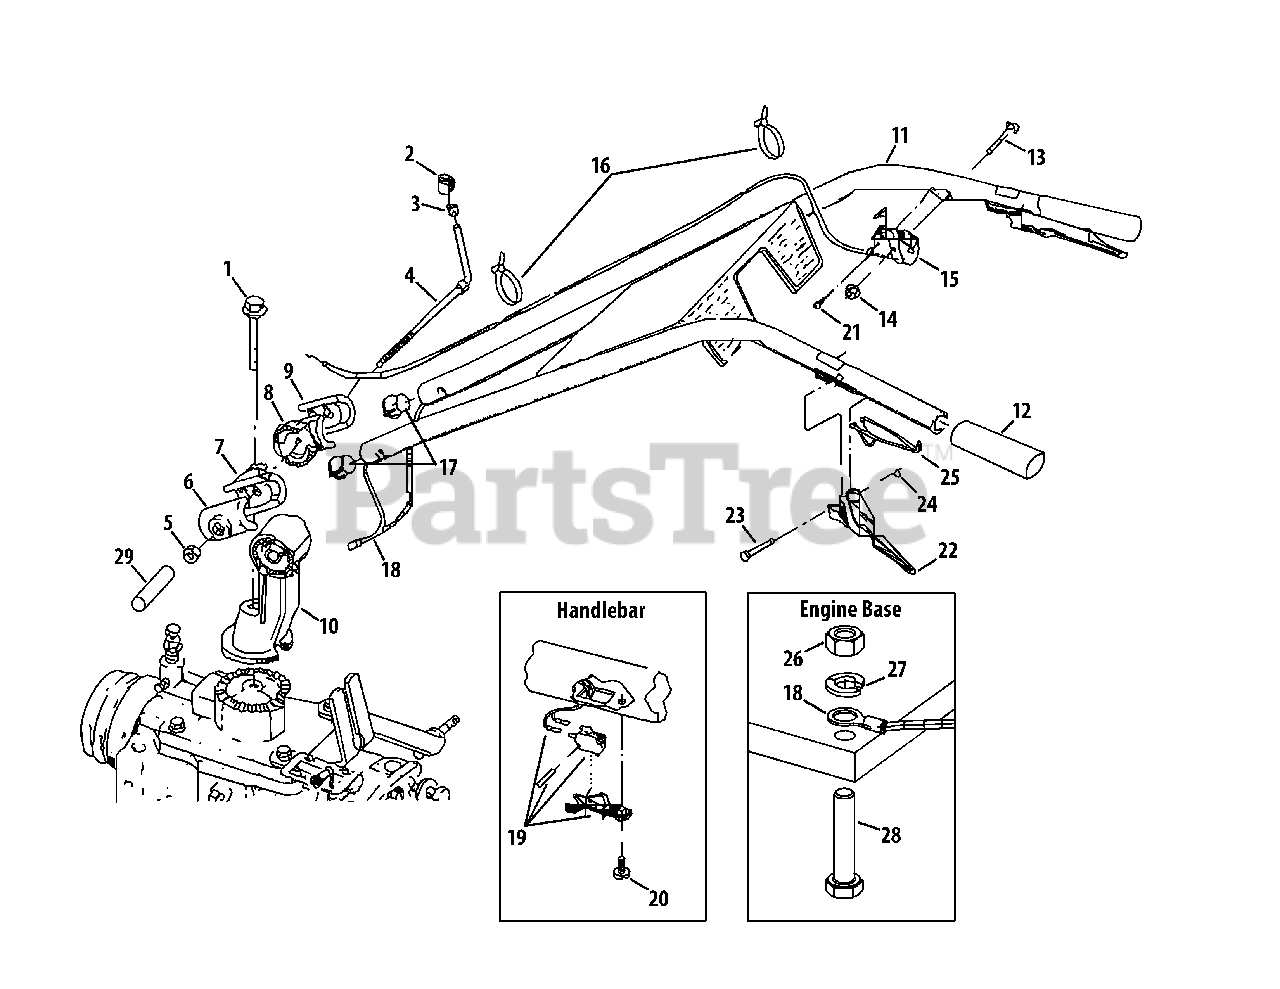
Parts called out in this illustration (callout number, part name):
1	Hex Bolt, 1/2-13 x 3-1/2
2	Handlebar Height Adjustment Knob
3	Retaining Ring
4	Handlebar Height Adjustment Stud
5	Hex Nut, 1/2-13
6	Handlebar Hgt, Adj. Clamp (LT)
7	Handlebar Hgt. Adj. Ratchet (LT)
8	Handlebar Hgt. Adj. Ratchet (RT)
9	Handlebar Hgt. Adj. Clamp (RT)
10	Handlebar Mounting Base
12	Handlebars Grip
13	Hex Cap Screw, 1/4-20 x 2.5
14	Hex Nut, 1/4-20
14	Flat Washer, .260 x .720 x .060
15	Throtle Control & Cable, 61"
16	Plastic Tie
17	Wire Harness Retainer Plug
18	Handlebar Wire Harness Assembly
19	Switch Assembly
20	Pan Head Screw, #10-16 x 1/2
21	Phillips Head Screw, 10-32 x 1/2
22	Operator Presence Control Lever
23	Pivot Pin
24	Retaining Ring
25	Return Spring
26	Hex Nut, 5/16-18
27	Washer, 5/16
28	Hex Head Screw, 5/16-18 x 1.5
